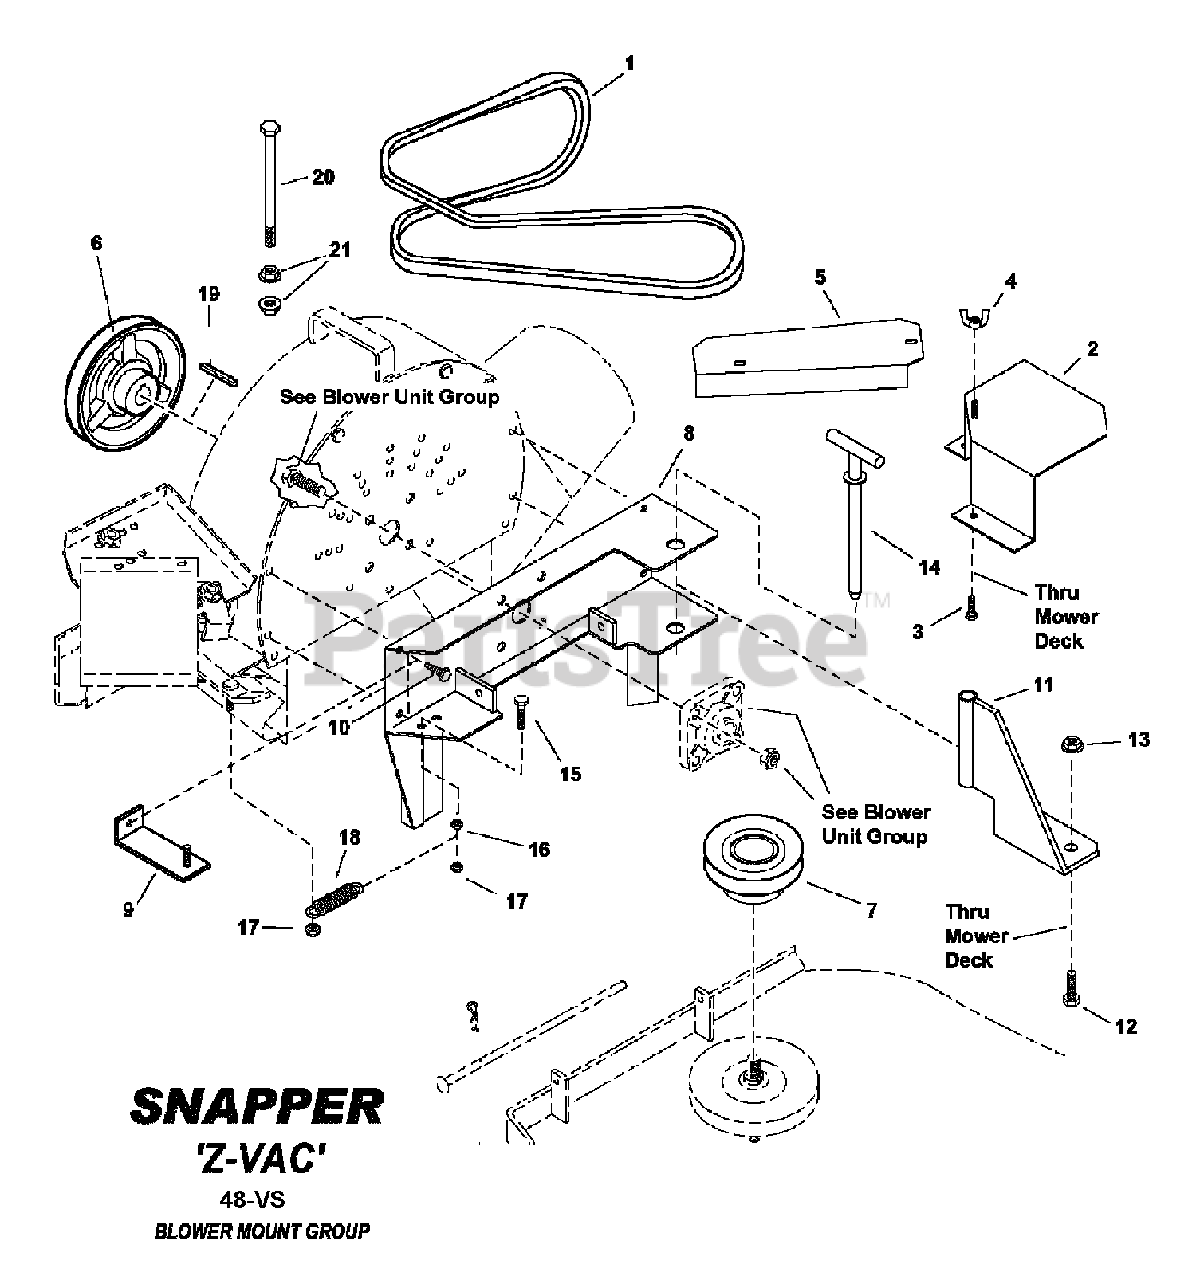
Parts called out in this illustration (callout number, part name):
1	BELT, A Section, 91.125" effective length
2	WELDMENT, Belt Cover, Deck
3	SCREW, 5/16-18 x 1-1/4" Hex Head Cap, GR5
4	WING LOCKNUT 5/16-18
5	BELT GUARD, 48" Deck
6	PULLEY, Blower Input, 48" & 52"
7	PULLEY, 48"/52" Spindle
8	WELDMENT, 48" Blower Mount
9	WELDMENT, Guard Support Bracket
10	SCREW, 5/16-18 x 3/4" Hex Washer Self-Tap
11	WELDMENT, Deck Mount Bracket
12	* SCREW, 3/8-16 x 1" Hex Head Cap, GR5
13	NUT, 3/8-16 Hex Flange Lock
14	WELDMENT, T-Handle Pin
15	* SCREW, 5/16-18 x 1" Hex Head Cap, GR5
16	NUT, 5/16-18 Hex Flange Lock
17	NUT, 5/16-18 Hex Center Lock, GR B
18	SPRING, Idler, Fast Vac
19	KEY, 1/4 Square x 1.44
20	SCREW, 3/8-16 x 6" Hex Head Cap, GR5
21	* NUT, 5/16-18 Hex Large Flange Center Lock
